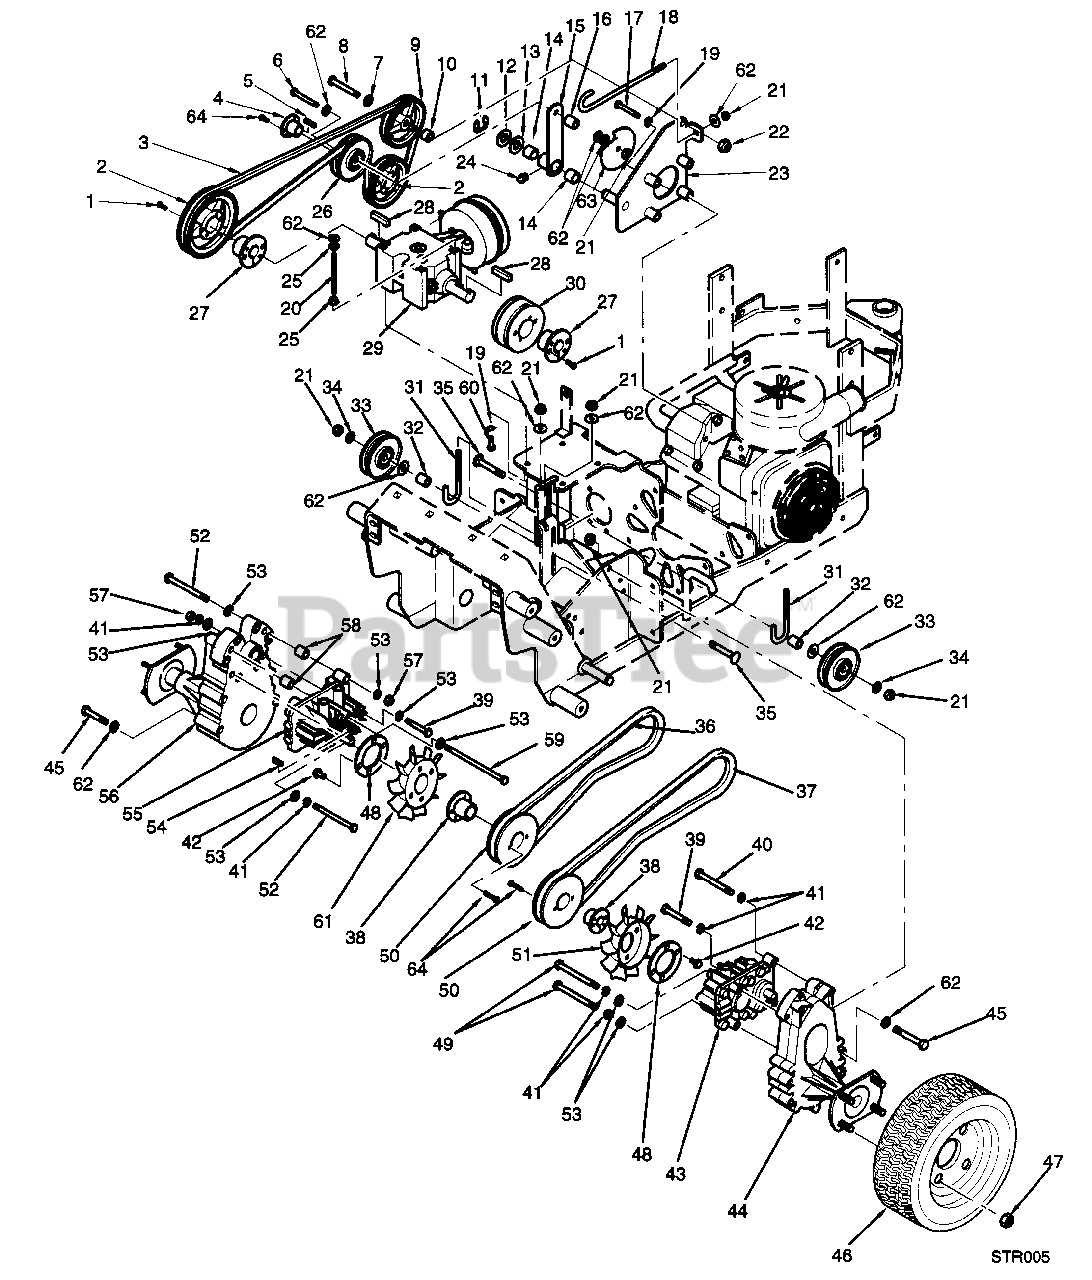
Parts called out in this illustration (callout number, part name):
1	BOLT, HEX HEAD, 1/4-20 X 1-3/8
2	PULLEY, 5.55 OD
3	BELT, DRIVE
4	HUB, TAPERED
5	KEY, 1/4 X 1/4 X 1-1/2
6	BOLT, HEX HEAD, 3/8-16 X 3-1/4
7	FLATWASHER, 1/2(.531 X .062 X .095)
8	BOLT, HEX HEAD, 1/2-13 X 3-1/4
9	PULLEY, IDLER - 5.75 DIA.
10	SPACER
11	RETAINING RING, .75 "E"
12	FLATWASHER, 3/8(.766 X 1.25 X .06)
13	FLATWASHER, 3/8(7.66 X 1.25 X .035)
14	BUSHING, OILITE, .753 ID
15	ARM, IDLER
16	SPACER, J-PULL ROD
17	BOLT, HEX HEAD, 3/8-16 X 2-3/4
18	ROD, J-PULL
19	LOCKWASHER, 3/8
20	STUD, 3/8-16 X 4.00
21	HEX LOCKNUT, ELASTIC STOP, 3/8-16
22	HEX LOCKNUT, ELASTIC STOP, 1/2-13
23	PIVOT, ENGINE IDLER
24	GREASE FITTING
25	SERR. FL. HEX NUT, 3/8-16
26	PULLEY, IDLER
27	HUB, TAPERED, 1.00 BORE
28	KEY, 1/4 X 1/4 X 1-1/4
29	GEARBOX, T-DRIVE
30	PULLEY, 4.25 OD DOUBLE GROOVE
31	ROD, J-PULL
32	SPACER, J-PULL
33	PULLEY
34	FLATWASHER, 3/8(.375 X 1.50 X .06)
35	CARRIAGE BOLT, 3/8-16 X 2-1/2
36	BELT, R.H. TRANSMISSION DRIVE
37	BELT, L.H. TRANSMISSION DRIVE
38	HUB, TAPERED, 15MM
39	BOLT, HEX HEAD, 5/16-18 X 1-3/4
40	BOLT, HEX HEAD, 5/16-18 X 2-1/2
41	LOCKWASHER, 5/16
42	SERR. FL. HEX HEAD CPSCR, 1/4-20 X 1/2
43	PUMP, L.H.
44	AXLE, L.H.
45	BOLT, HEX HEAD, 3/8-16 X 3-3/4
46	WHEEL ASSEMBLY, DRIVE
47	NUT, WHEEL
48	BACK-UP WASHER, FAN
49	BOLT, HEX HEAD, 5/16-18 X 5-1/2
50	PULLEY, 4.25 OD
51	FAN, COOLING LH
52	BOLT, HEX HEAD, 5/16-18 X 4-1/2
53	FLATWASHER, 5/16(.344 X .688 X .065)
54	KEY, 5 MM X 5 MM X 25 MM
55	PUMP, R.H.
56	AXLE, R.H.
57	HEX NUT, 5/16-18
58	SPACER
59	BOLT, HEX HEAD, 5/16-18 X 7-1/2
60	BOLT, HEX HEAD, 3/8-16 X 1.0
61	FAN, COOLING RH
62	FLATWASHER, 3/8(.391 X .938 X .105)
63	WASHER, HEAT DEFLECTOR
64	SOCKET HEAD CAPSCREW, 1/4-20 X 1-3/8
